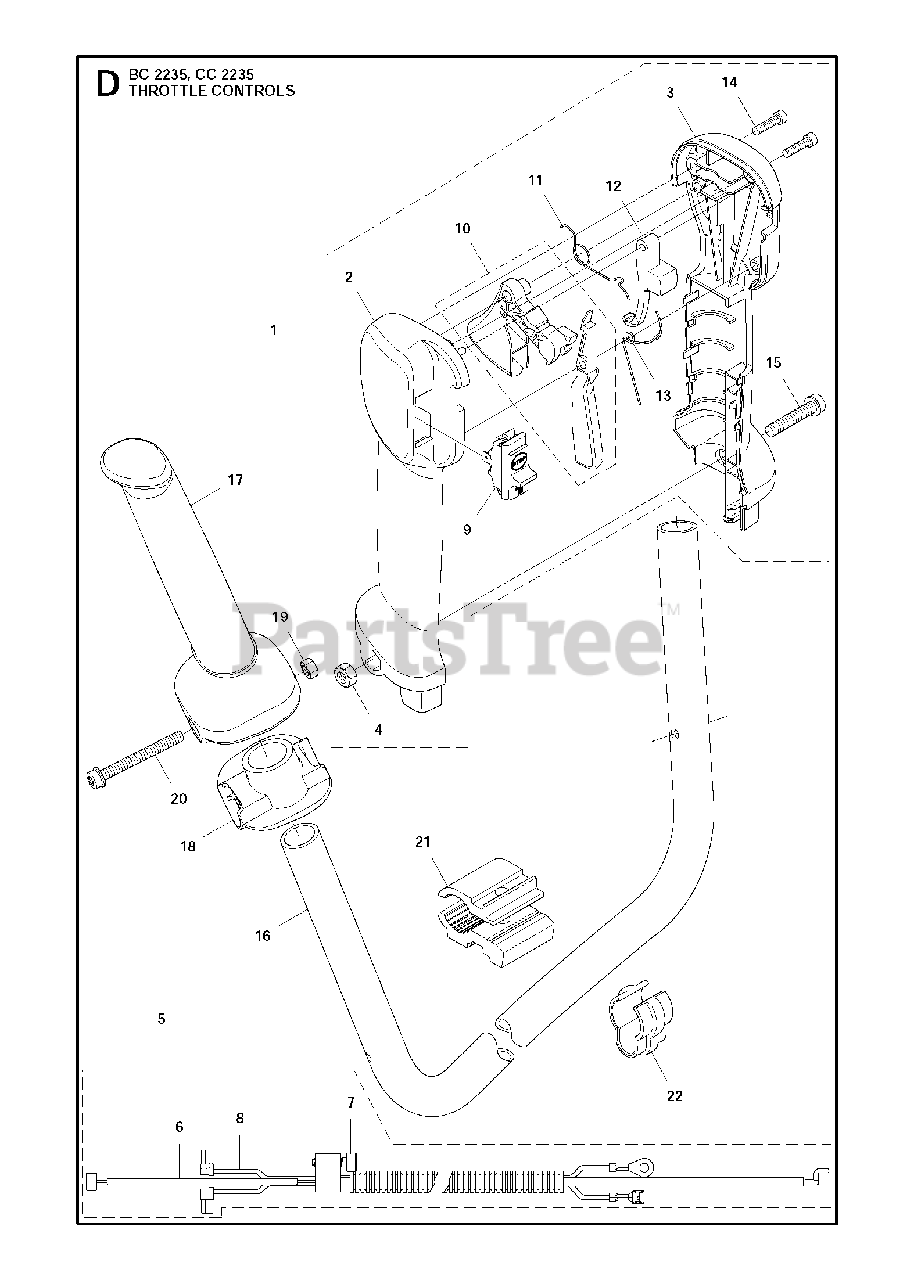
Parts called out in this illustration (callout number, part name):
2	HANDLE LEFT
3	HANDLE RIGHT
4	NUT
5	WIRING KIT COMPLETE
6	THROTTLE WIRE
7	SCREW
8	SHORT CIRCUIT CABLE
9	STOP BUTTON
10	THROTTLE CONTROL
11	SPRING
12	STARTER THROTTLE LOC
13	SPRING
14	SCREW
15	%SCREW
